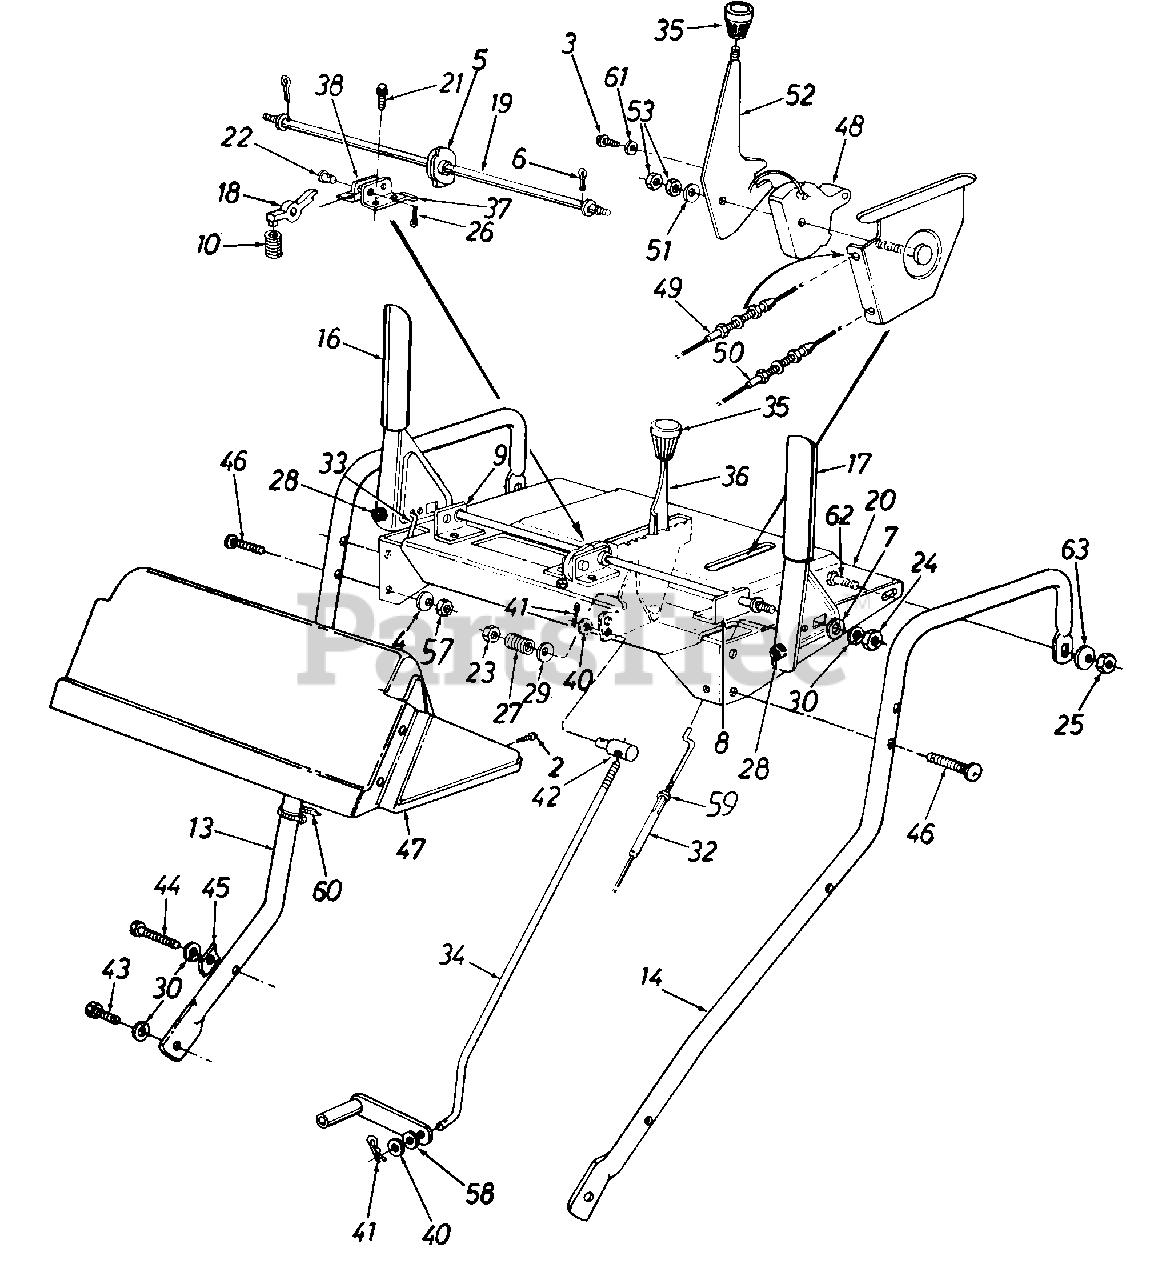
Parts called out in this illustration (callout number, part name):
2	Truss Mach. B-Tap Scr. #10 x .5
3	Hex AB-Tap Scr. 1/4 x .62" Lg.
4	Bell-Wash. .325" I.D. x .88" O.D.
5	Cam Handle Lock
6	Cotter Pin 3/32" Dia. x .75" Lg.
7	Washer (Special) .72" O.D.
10	Compression Spring
13	Handle--R.H.
17	Engagement Handle--L.H.
18	Pawl Handle Lock
22	Clevis Pin .437" Dia. x .65" Lg.
23	Hex Ins. L-Nut 3/8-24 Thd.
24	Hex Nut 5/16-18 Thd.
25	Hex Nut 1/4-20 Thd.
26	Cotter Pin 3/32" Dia. x 1" Lg.
27	Compression Spring
28	Rubber Bumper
29	Bell-Wash. .38" I.D. x .88" O.D.
30	L-Wash. 5/16" I.D.
32	Auger Clutch Cable
33	Drive Clutch Cable
34	Shift Rod
35	Shift Knob
36	Shift Handle
40	Fl-Wash. .344" I.D. x .62" O.D.
41	Internal Cotter Pin 5/16" Dia.
42	Ferrule
43	Hex Bolt 5/16-18 X .62" Lg. (Special)
44	Hex Bolt 5/16-18 X 1.75" Lg. (Gr. 5)
45	Handle Tab
46	Curved Carr. Bolt 5/16-18 X 1.5" Lg.
47	Handle Panel
48	Cable Guide
49	Chute Control Cable
50	Chute Control Cable w/Clip
51	Bell-Wash. .325" I.D. x .93" O.D.
53	Hex Cent. L-Nut 5/16-18 Thd.
57	Hex Nut 5/16-18 Thd.
58	Spr. Wash. .32" I.D. x .62" O.D.
59	Hex Nut #10-24 Thd.
60	Cable Tie
61	Washer (Special) 1.25" O.D.
62	Hex Bolt 1/4-20 X .85" Lg.
63	Bell-Wash. .265" I.D. x .75" O.D.
